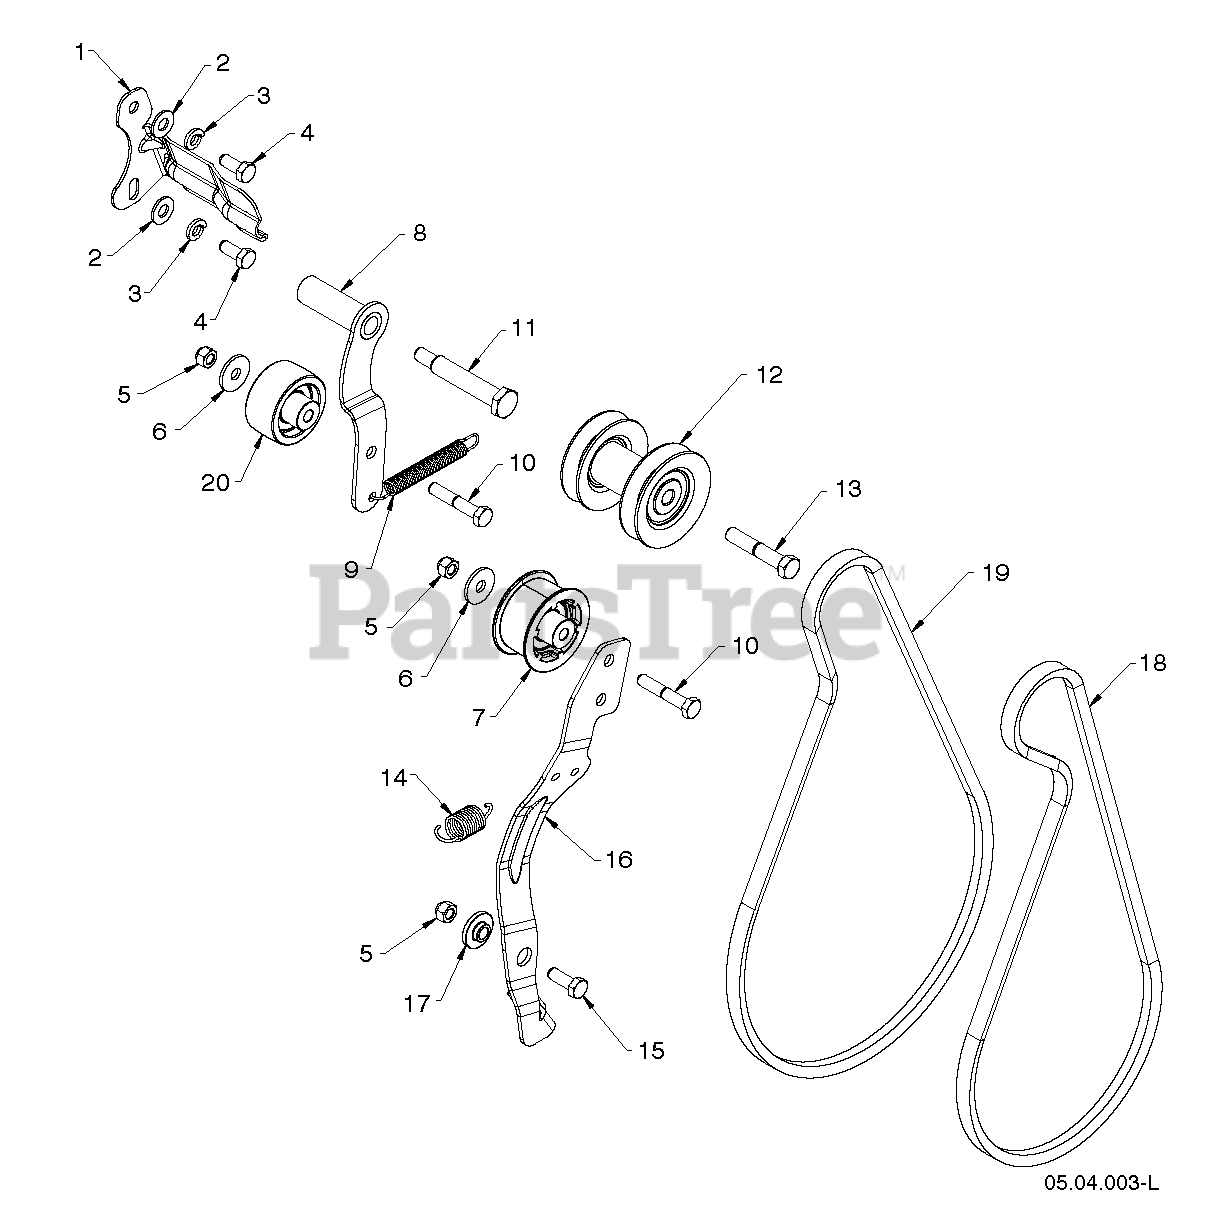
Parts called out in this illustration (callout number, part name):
1	BELT KEEPER BRACKET
2	WASHER M
3	LOCKWASHER
4	SCREW 5/16-24 X .75 GR5
5	NUT.71038.31-18.HEX.NYLOCK
6	STEEL WASHER
7	PULLEY,IDLER,2.00 W SPA
8	ARM IDLER DRIVE WELDMENT_HOT
9	SPRING RETURN IDLER ARM
10	BOLT, HEX 5/16-18X1-3/4
11	BOLT 5/16-24X2.25 HEX HEAD SHO
12	PULLEY.ASM.IMPELLER/DRIVE
13	BOLT.BLADE
14	SPRING RETURN, IDLER ARM, IMPE
15	BOLT
16	BRACKET ARM.IDLER.IMPELLER ARM
17	BUSHING.BRAKE.ARM
18	BELT.AUGER.HI.CRANK
19	BELT.HIGH.CRANK.4LX41.RAW.EDGE
20	PULLEY.IDLER.FLANG.2.O/SPACER
